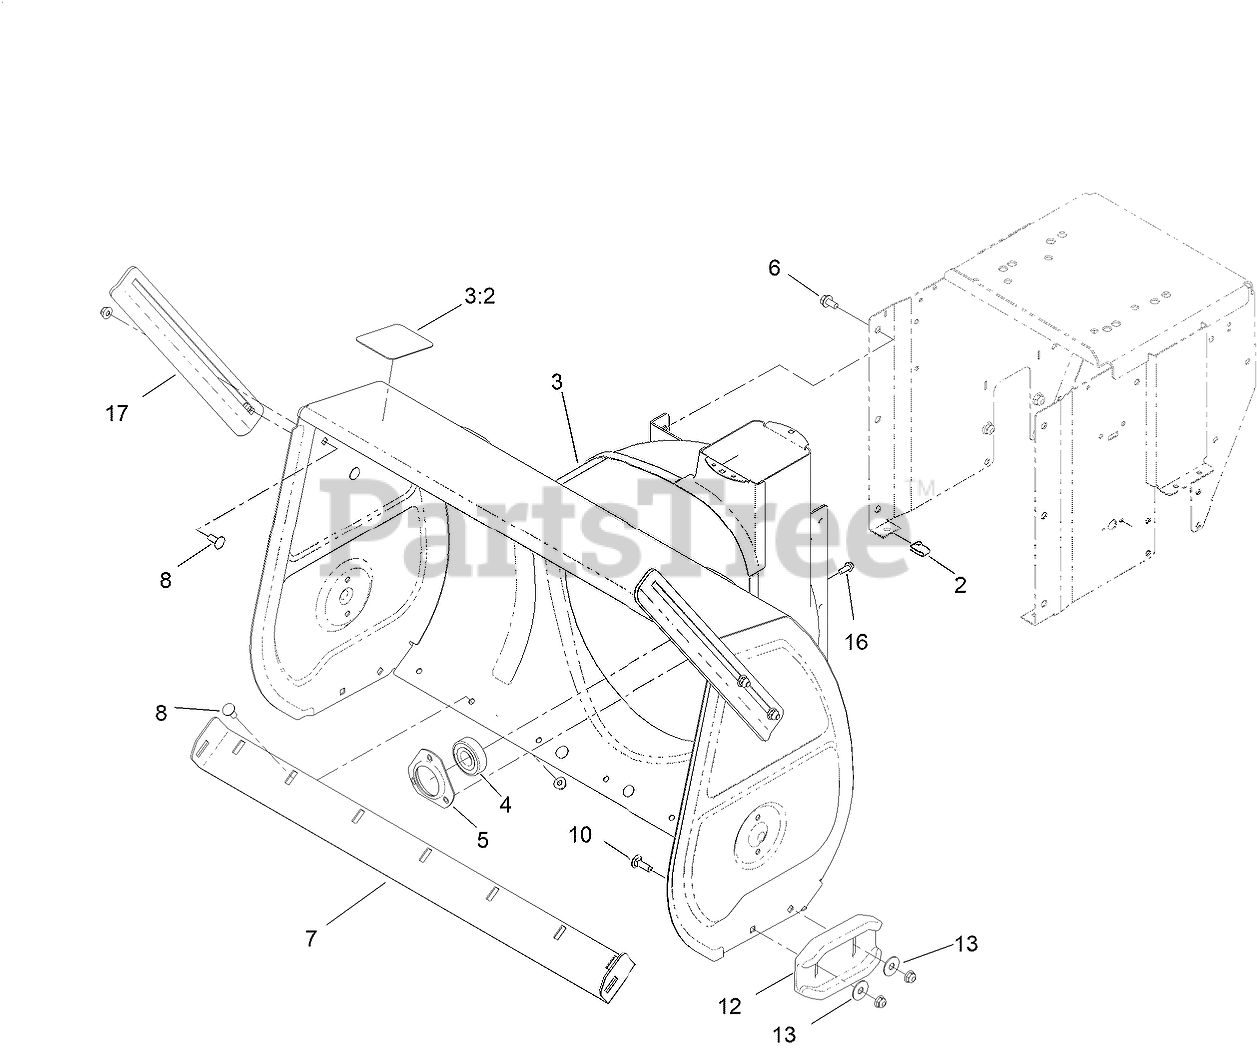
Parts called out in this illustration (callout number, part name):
3	AUGER HOUSING ASM
3:2	DECAL-DANGER, AUGER
4	BEARING-BALL
5	RETAINER-BEARING
6	SCREW-HWHTF
7	BLADE-SCRAPER
8	BOLT-CARR
10	BOLT-CARR
12	SKID-CAST
13	WASHER-FLAT
16	SCREW-HWH
17	BREAKER-DRIFT, SIDE
